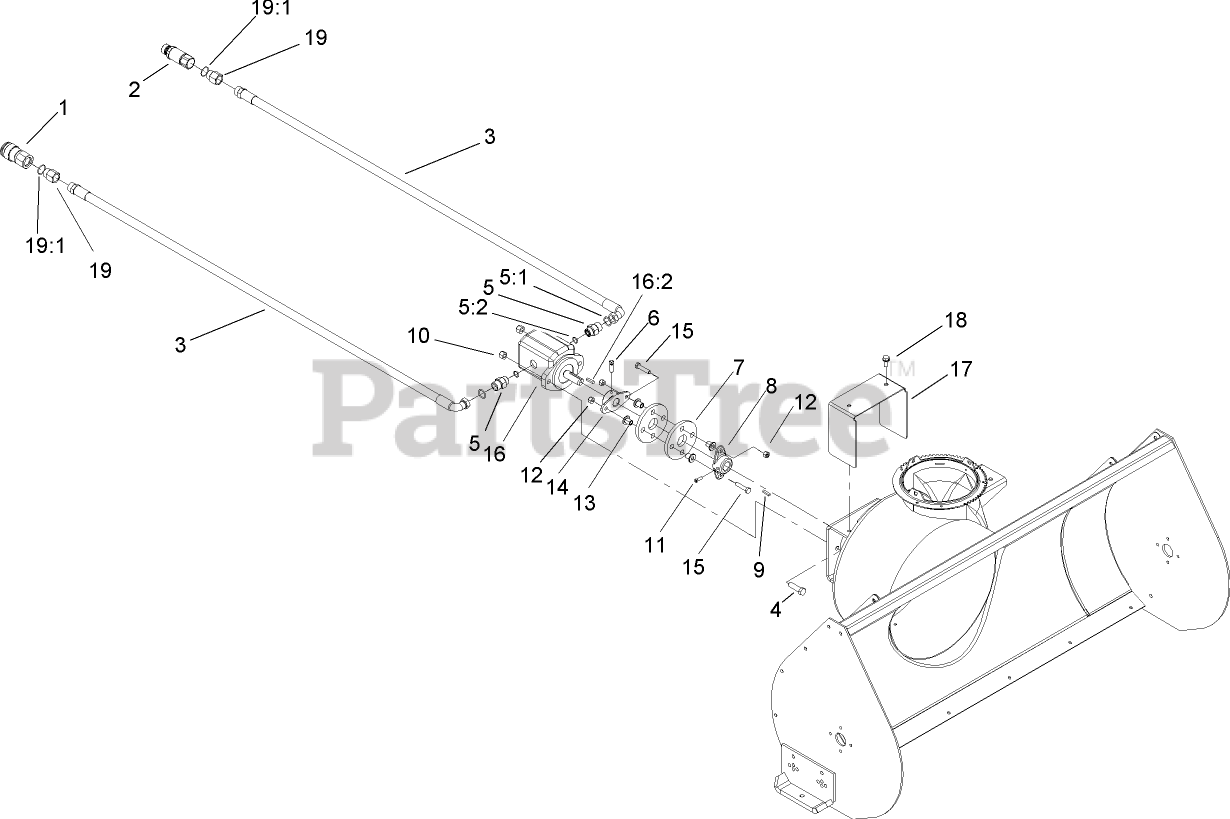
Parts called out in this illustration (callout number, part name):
1	COUPLER-FACE, FLUSH
2	NIPPLE-CONNECT, PRESSURE
3	HOSE-HYD
4	SCREW-HH
5	FITTING-STRAIGHT
5:1	O-RING
5:2	O-RING
6	SCREW-SET
7	COUPLING-RUBBER
8	HUB-COUPLER
9	KEY
10	NUT-LOCK, NI
11	SCREW-SET, SQH
12	NUT-LOCK, NI
13	SPACER
14	HUB-PUMP
15	SCREW-HH
16	MOTOR-HYDRAULIC
16:2	KEY-SQUARE
17	SHIELD-MOTOR
18	SCREW-HWHTF
19	ADAPTER-HYD
19:1	O-RING
